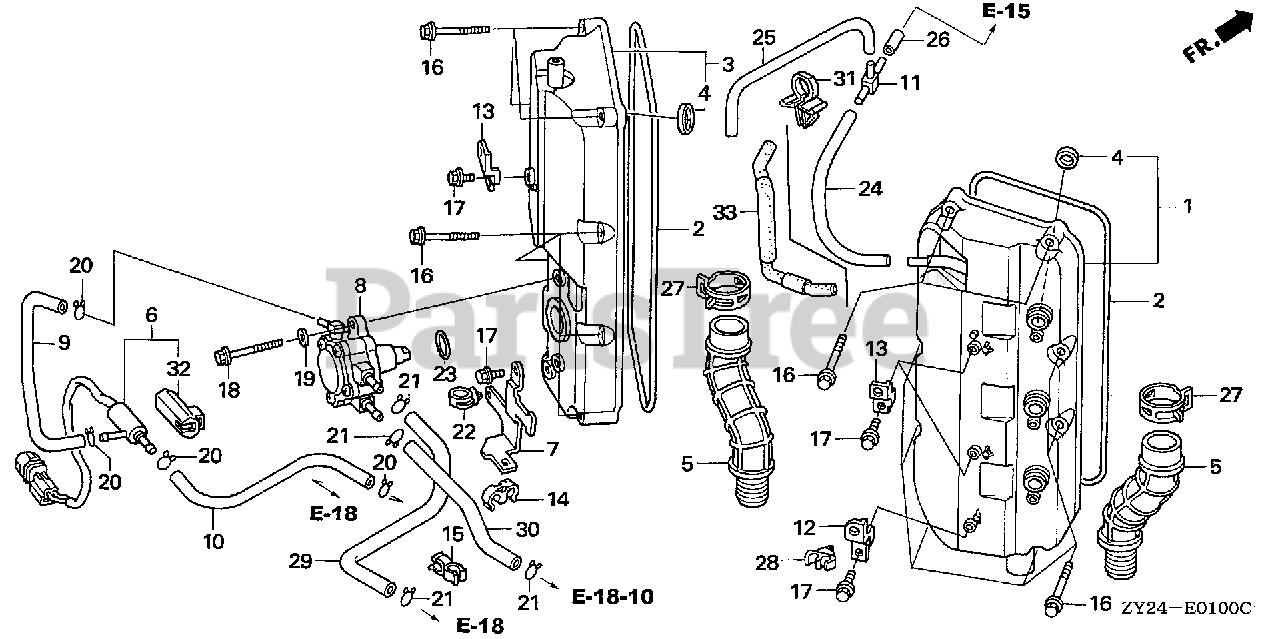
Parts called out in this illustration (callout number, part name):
1	COVER, R. CYLINDER HEAD *NH8* (DARK GRAY)
2	GASKET, HEAD COVER
3	COVER, L. CYLINDER HEAD *NH8* (DARK GRAY)
4	SEAL, SPARK PLUG TUBE (NOK)
5	TUBE, OIL
6	VALVE ASSY., SOLENOID
7	BRACKET, SOLENOID VALVE
8	PUMP ASSY., FUEL (MSDS)
9	TUBE D, FUEL
10	TUBE E, FUEL
12	BRACKET, CLIP B
13	BRACKET C, HARNESS CLIP
14	CLIP, SENSOR HOSE
15	CLIP, SHIFT WIRE
16	BOLT, FLANGE (6X35)
17	BOLT, FLANGE (6X14)
18	BOLT, FLANGE (8X32)
19	WASHER, PLAIN (8MM)
20	CLIP, TUBE (B10)
21	CLIP, TUBE (B12)
22	CLIP, HARNESS
23	O-RING (37X2.4) (ARAI)
24	TUBE A, BREATHER
25	TUBE B, BREATHER
26	TUBE C, BREATHER
27	CLAMP, TUBE (D32.5)
28	CLIP D, WASHER TUBE
29	TUBE F, FUEL
30	BULK HOSE, FUEL (7.5X8000) (7.3X380)
31	CLIP A, WIRE
32	GROMMET, SOLENOID VALVE
33	TUBE A, BREATHER
